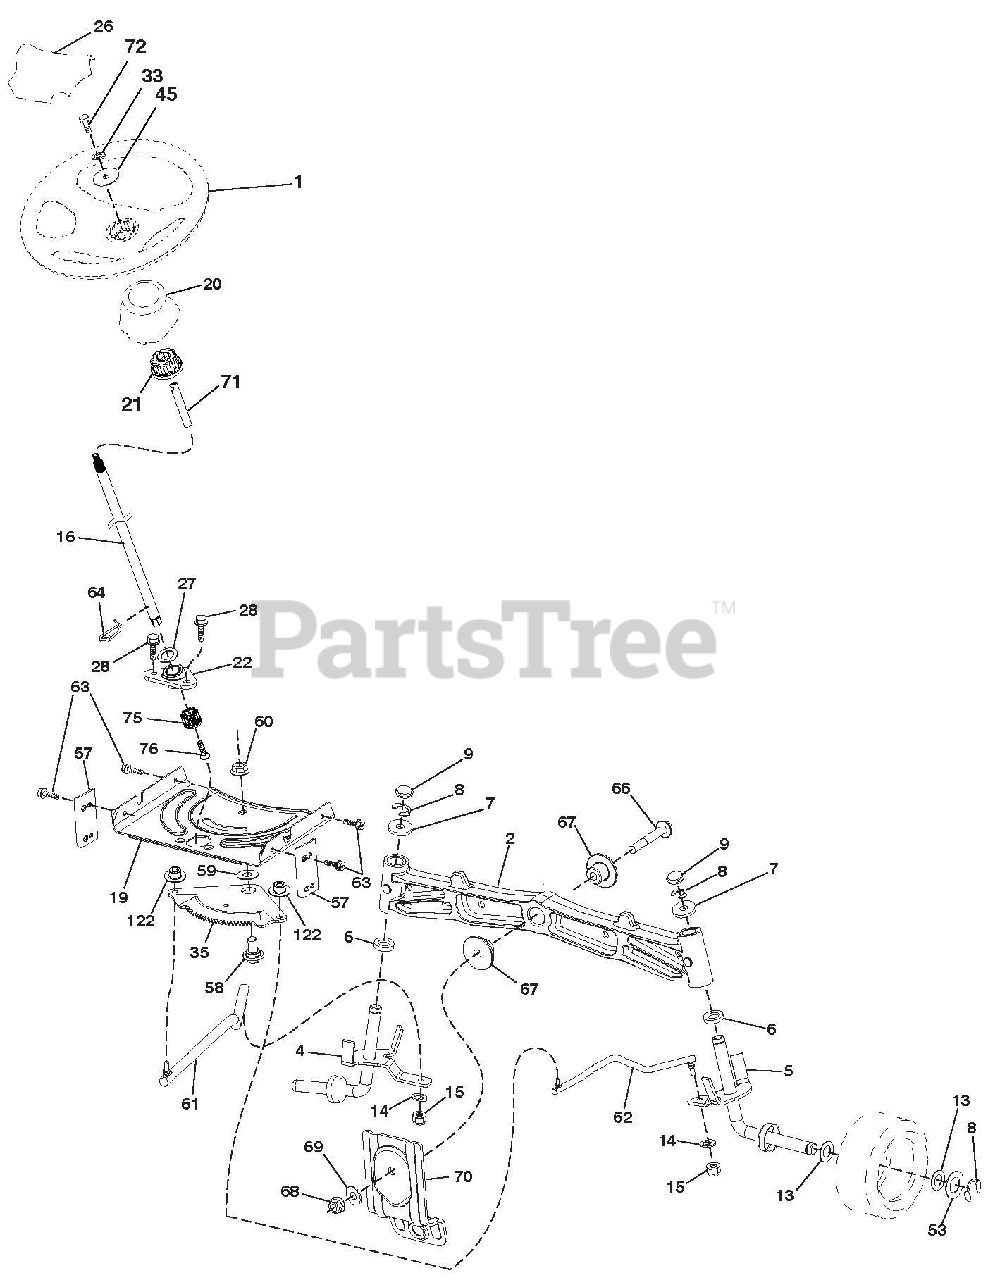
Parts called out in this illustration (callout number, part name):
1	WHEEL.STEERING.HARD RIM.BLACK
2	AXLE.CAST IRON
4	SPINDLE.WELDED.LH.15"TEX
5	SPINDLE.WELDED.RH.15"TEX
6	WAHSER THRUST .75 X 1.230
7	WASHER.25/32 X 1-5/8 X 16GA.
8	RING.KLIP.#T5304-75
9	CAP.SPINDLE.FR.TOP.BLK.
13	WASHER.25/32 X 1 1/4 X 16 GA.
14	Washer, Lock 3/8
15	NUT.CROWNLOCK.3/8-24
16	STEERING SHAFT
19	PLATE.STEER.DDL.NLT/NGT
20	BOOT.STEERING
21	ADAPTER.WHEEL.STRG..760
22	STEER.SUPT. LOWER
26	CAP WHEEL STEERING HRS/SRS BLK
27	Washer 21/32 x 1 x 16 Ga.
28	SCREW.HEXWSH THDR3/8-16X3/4.BL
33	Washer, Lock 5/16
35	GEAR SECTOR.PLATE.DDL.NLT/NGT
45	WASHER.11/32ID X2 3/8OD X 12GA
53	WASHER.HARDEN..793 X 1.637X060
57	BRACKET.UPSTOP.TEX
58	BOLT.SHOULDER.SECTOR.PIVOT.CFM
59	WASHER.THRUST.SECTOR.STEER.NLT
60	NUT.FLANGE LOCK.5/8-11
61	DRAGLINK.LH.BALLSTUD.DDL.
62	DRAGLINK.RH.BALLSTUD.DDL
63	SCREW.5/16-18X3/4.SMGML.TAP/BL
64	RETAINER.CLIP.SPRING.STEERING
66	BOLT.HEX.FGHD.7/16-14 X 3.SERR
67	BUSHING.PM.FRONT AXLE
68	NUT.LOCK.FLANGE.7/16-14.GR5
69	WASHER.1.5 X .505 X .118
70	BRACKET.DECK.SUSPENSION.FRONT
71	Extension Steering
72	Bolt 5/16-18 x 14 w/Patch
75	PINION
122	CAP GEAR SECTOR
